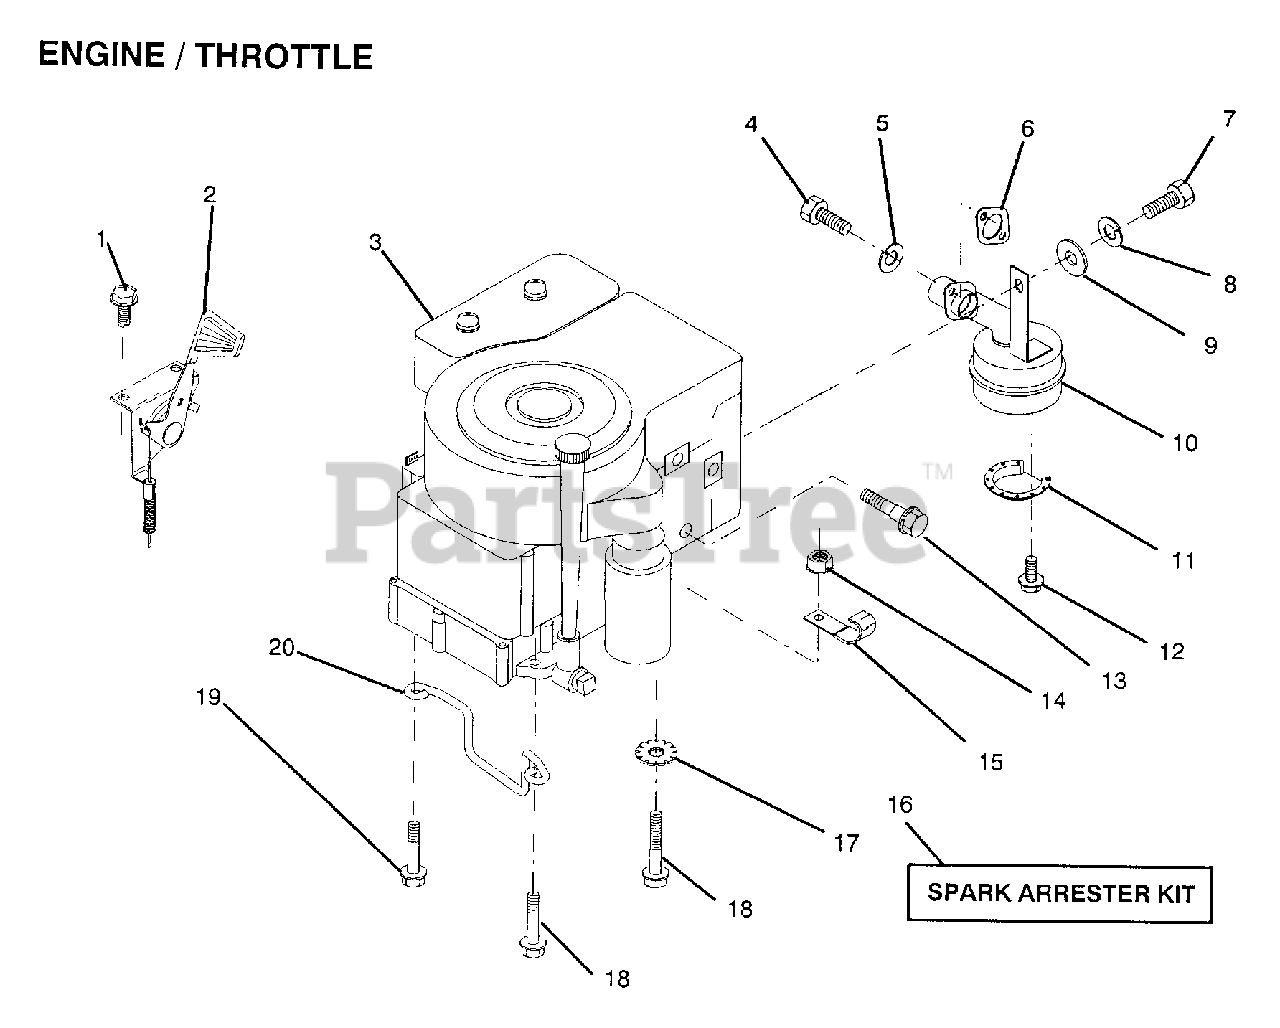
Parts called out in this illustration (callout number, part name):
1	SCREW
3	ENGINE 12 HP
4	SCREW
5	LOCKWASHER
8	LOCKWASHER
11	DEFLECTOR.222573
13	BOLT T
14	NUT
15	CLIP T
17	LOCKWASHER
18	SCREW LT
19	SCREW LT
20	"KEEPER,DR BELT GR"
